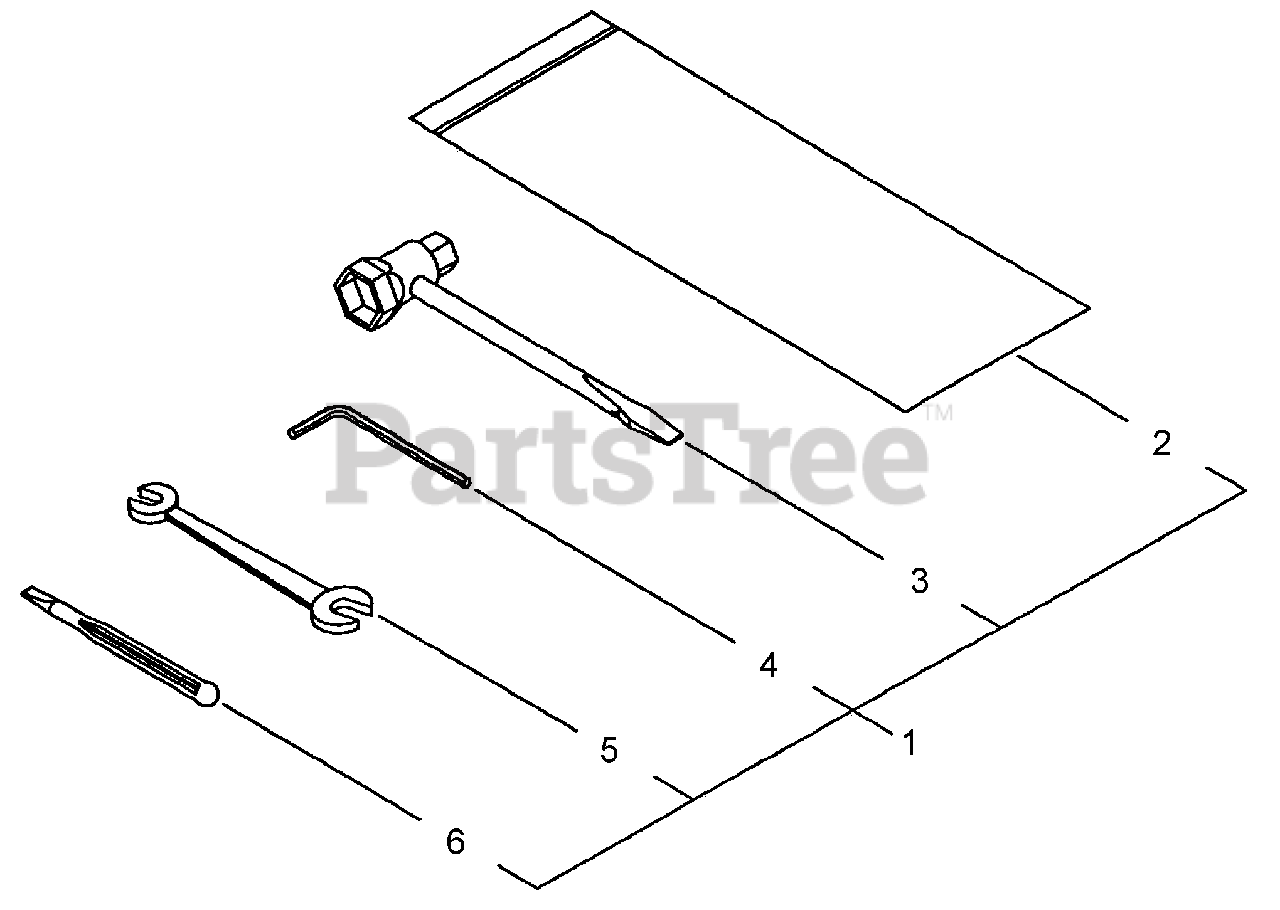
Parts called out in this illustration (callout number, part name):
1	TOOL KIT
2	BAG, TOOL
3	T-WRENCH - 13X19mm
4	HEX KEY - 3mm
5	HEX KEY - 4mm
6	SCRAPER
